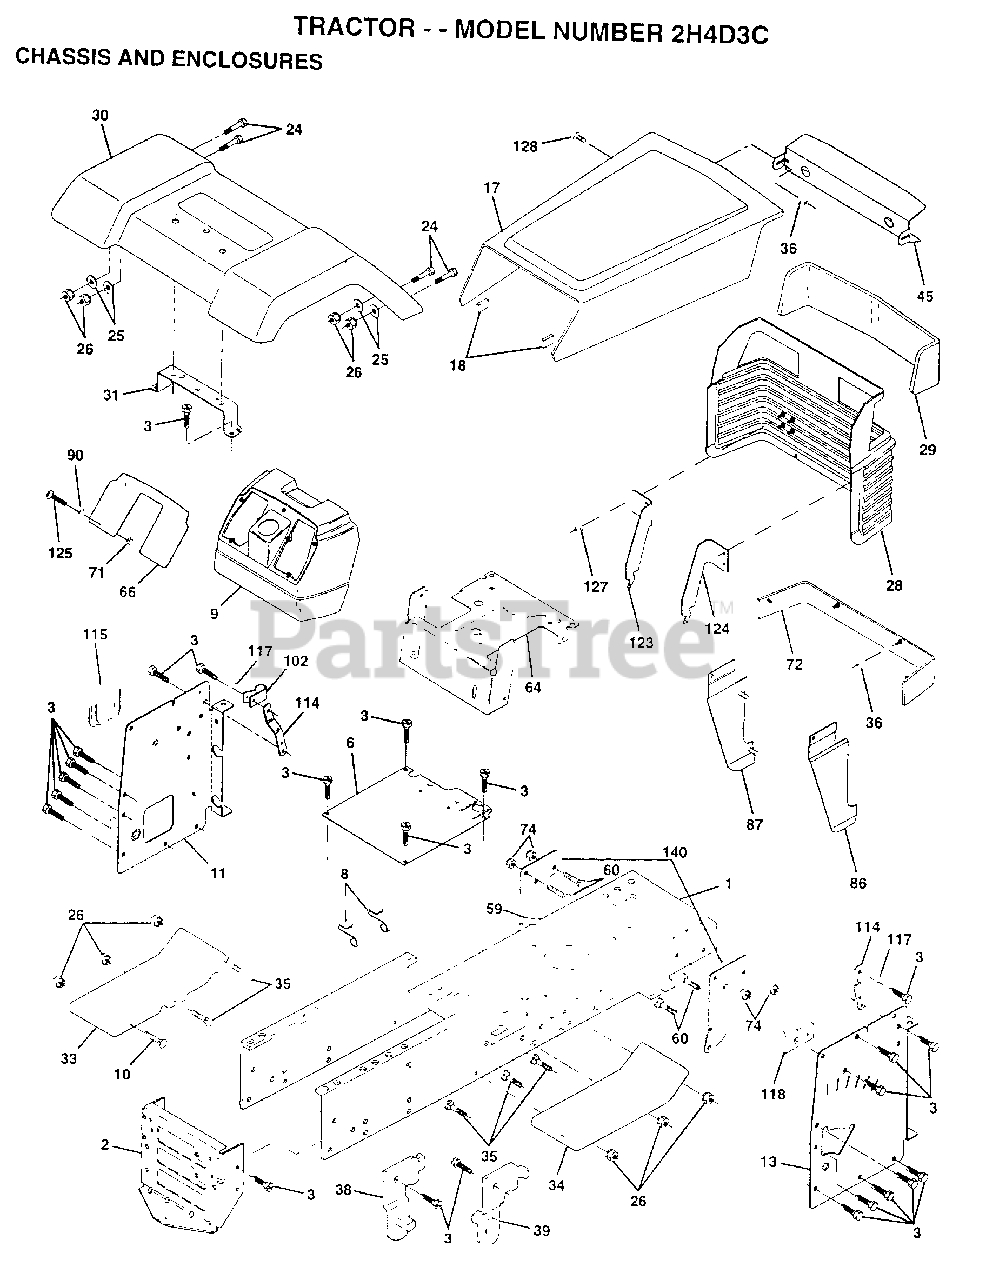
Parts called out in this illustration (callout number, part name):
1	CHASSIS WLDMT 11G
3	SCREW
8	"CLIP,INSULATOR"
9	DASH.PLASTIC.BLK
11	PANEL.DASH.LH.
13	PANEL.DASH.RH.NOT
17	HOOD.ASM.YTGT.PNT
24	BOLT
25	WASHER
26	NUT
28	GRILLE ASM WELD
30	FENDER
31	BRKT FENDER
33	FOOTREST LH
34	FOOTREST RH
35	BOLT
36	PAL NUT LT
38	BRACKET ASM LH
39	BRACKET ASM RH
60	BOLT
64	DASH.LOWER.LT
66	PLATE DASH SILKSC
71	NUT HXKEP 1/4X20
72	STRAP GRILLE 505
86	PANEL.SIDE.RH.ASM
87	PANEL.SIDE.LH.ASN
90	WASHER PM
102	CLIP T
114	BRACKET.SUPT.DASH
115	COVER ACCESS
117	WASHER.SERRATED.
118	BRACKET.CLUTCH.MC
123	BRACKET.PICK.LH.
124	BRACKET.PICK.RH.
125	SCREW
127	PAL NUT
128	SCREW SPECIAL
